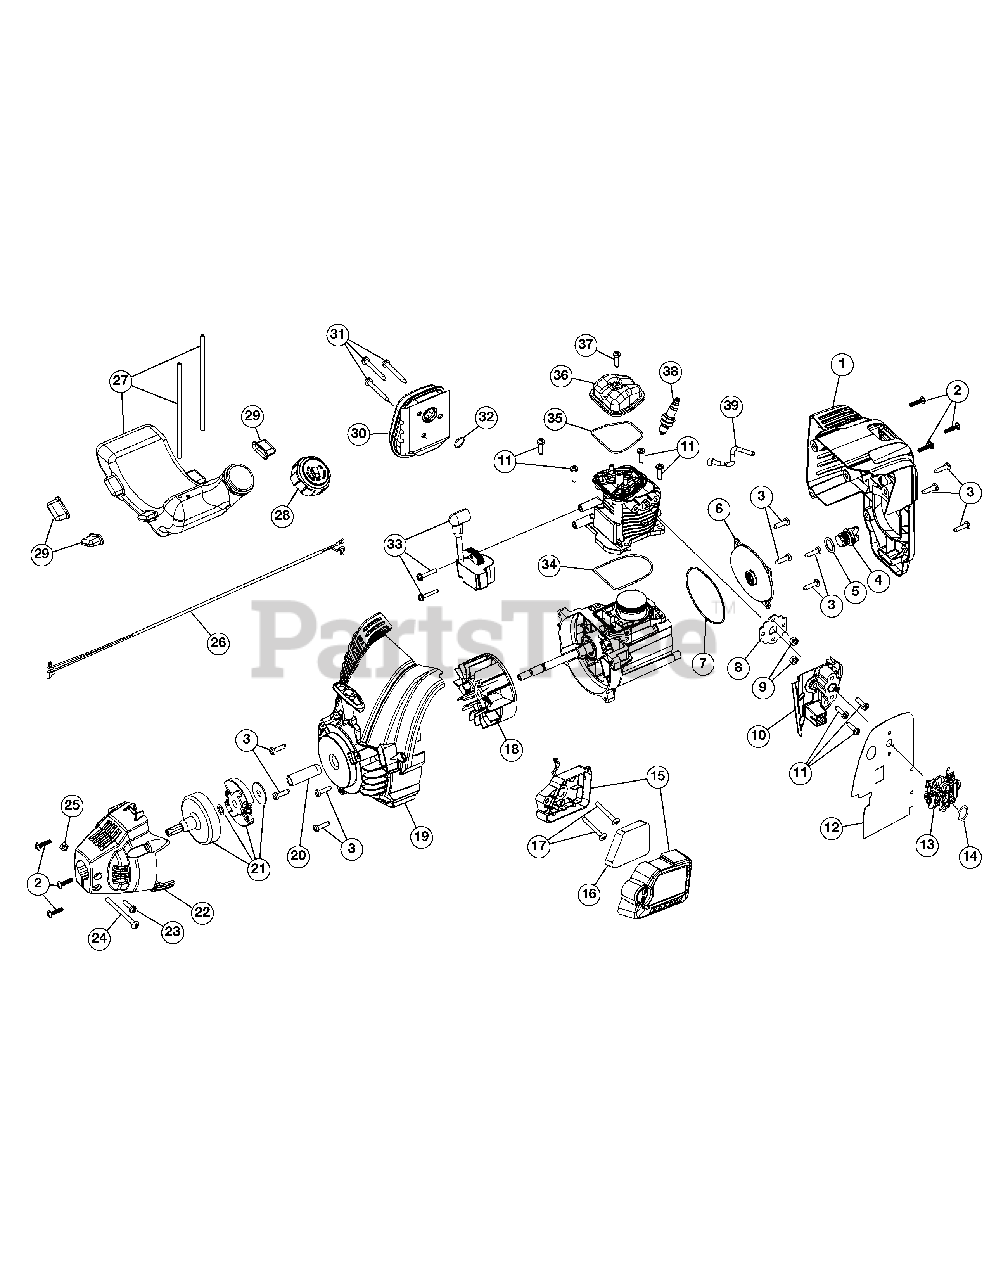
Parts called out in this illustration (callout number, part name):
1	Engine Cover Assembly (Incl. 2 & 3)
2	Cover Screw
3	Starter Screw
4	Oil Plug (Incl. 5)
5	Oil Plug O-Ring
6	Crank Case Cover
7	Crank Case Cover O-Ring
8	Insulator Gasket
9	Insulator Nut
11	Screw
12	Carburetor Gasket
13	Carburetor (with Primer)
15	Air Cleaner Cover Assembly (Incl. 16)
16	Air Filter
17	Air Filter Screw
18	Flywheel Assembly
19	Starter Housing Assembly (Incl. 3)
21	Clutch Assembly
22	Clutch Cover (Incl. 2)
23	Anti-Rotation Screw
24	Clamp Screw
25	Clamp Nut
26	Lead Wires
27	Fuel Tank Assembly w/Fuel Lines (Incl. 28)
29	Fuel Tank Pads
30	Muffler Assembly (Incl. 31 & 32)
31	Muffler Screw
32	Muffler Gasket
33	Module Assembly
34	Cylinder O-Ring
35	Rocker Cover O-Ring
36	Rocker Cover
37	Rocker Cover Screw
38	Spark Plug
39	Breather Hose
